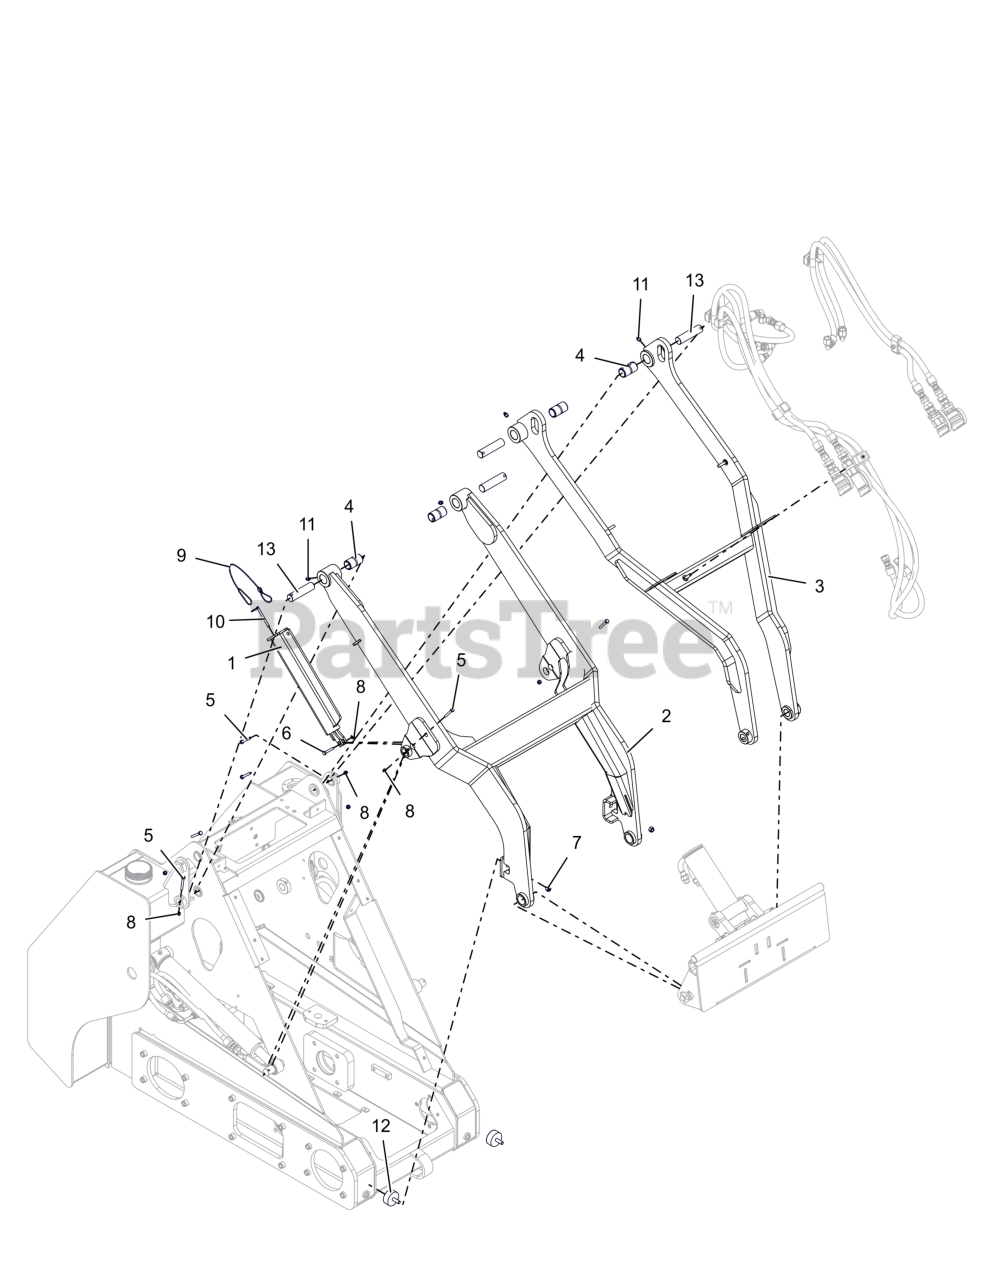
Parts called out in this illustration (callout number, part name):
1	LOCKOUT, LIFTARM
2	ARM, LIFT - W/SAFETY DECALS
3	ARM, PARALLEL (BLACK)
4	BSHG, HARDENED 1.25ODX1.00IDX2.25LG
5	BLT, HEX .25-20X2.00 G5 ZCC
6	BLT, HEX 0.25-20X1.5 GR8 ZCC
7	NUT,NYL .38-16 G5 ZCC
8	NUT,NYL .25-20 G5 ZCC
9	LANYARD, LOCKING
10	PIN, DETENT - W/RING .25X2.5
11	FITTING, GREASE
12	BUMPER, RUBBER
13	PIN, PIVOT
